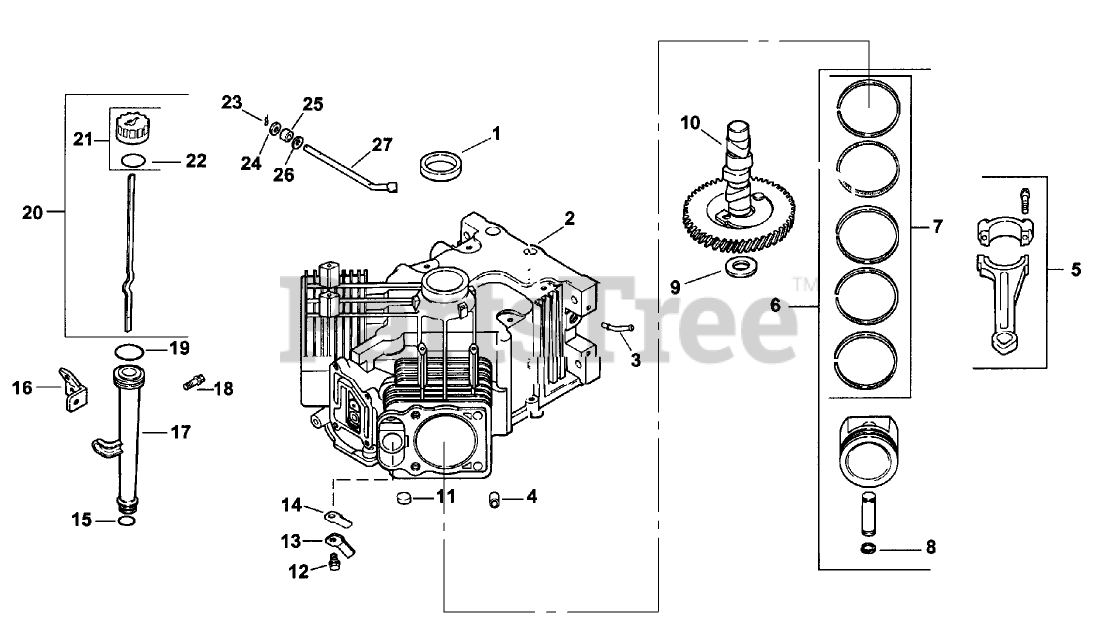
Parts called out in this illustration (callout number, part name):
1	SEAL-OIL
2	Use:Short Block or Miniblock
3	Fitting
4	Pin, dowel locating
5	Rod-Connecting (Standard)
6	Piston w/Ring SetStd. (Includes 7-8)
7	Ring Set (.25)
8	RETAINER-PIN, PISTON
9	SHIM-CAMSHAFT (RED .032)
10	Camshaft Kit
11	PLUG-CUP
12	Screw
13	RETAINER-REED, BREATHER
14	Reed-Breather
15	O-RING
16	BRACKET-TUBE, OIL FILL
17	OIL FILL TUBE KIT
18	Screw, hex. flange
19	O-RING
20	Dipstick assembly (Includes 21,22)
21	Kit, oil fill cap (Includes 22)
22	O-Ring
23	Pin-Hitch
24	Washer-Flat
25	Seal-Cross Shaft, Governor
26	WASHER-FLAT (1/4)
27	Shaft-Governor Cross
